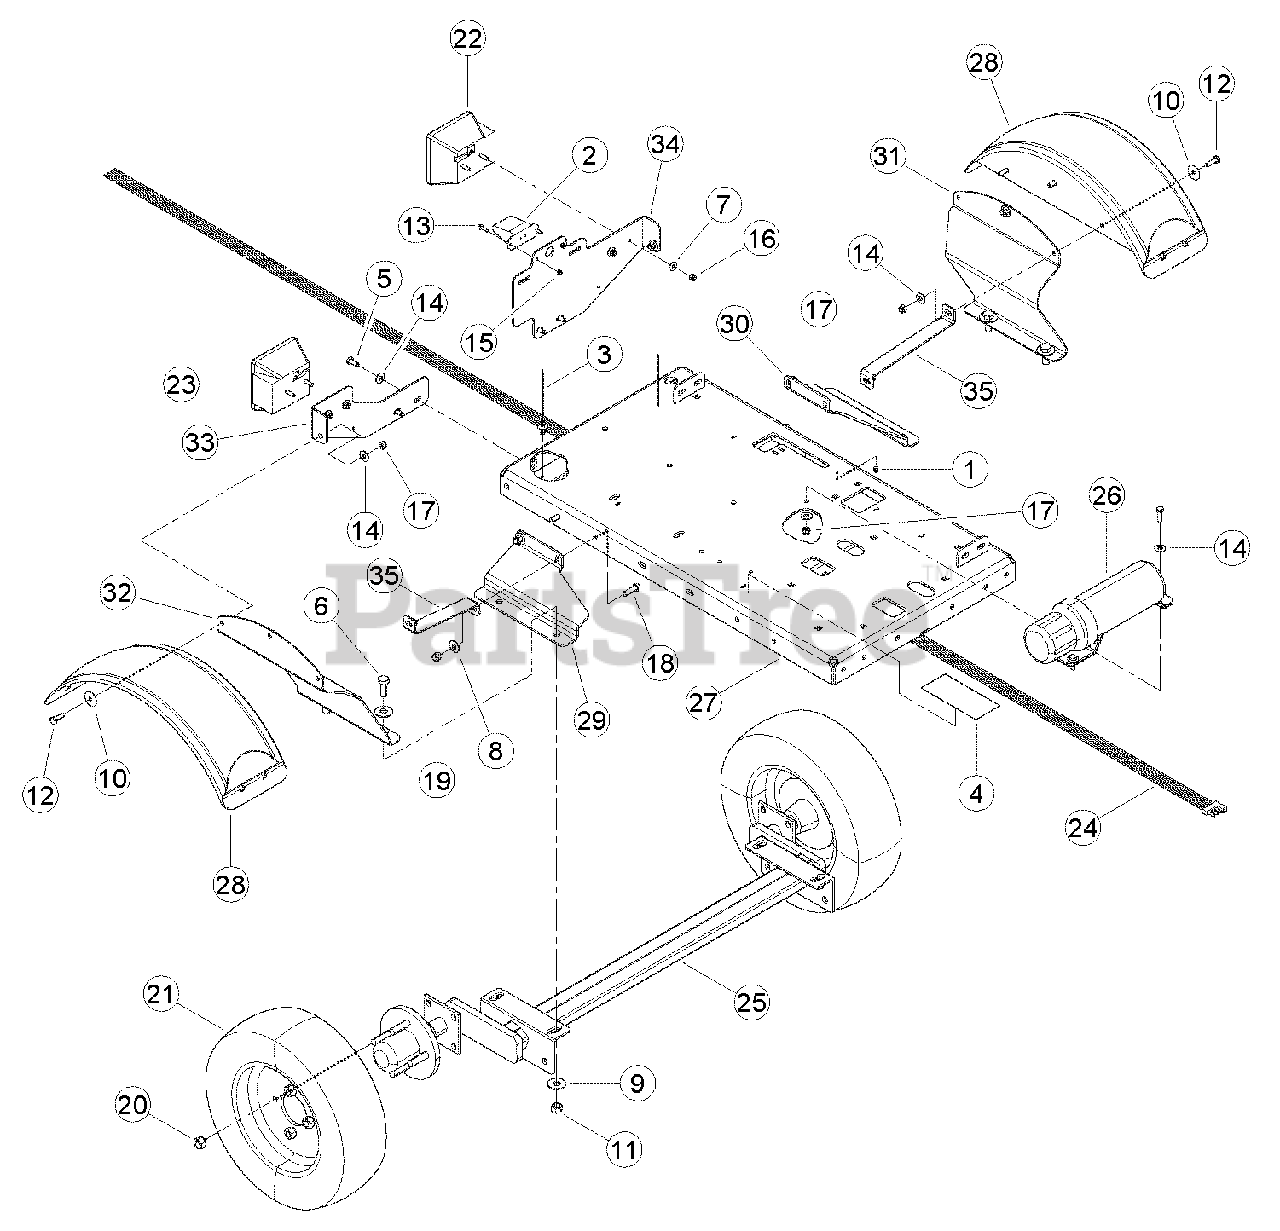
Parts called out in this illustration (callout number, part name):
1	FITTING, 1/4 SELF-TAP GREASE
2	LIGHT, LICENSE PLATE
3	TIE, DOME FIR TREE
4	DECAL, MUTILINGUAL MANUAL
5	BOLT, 5/16 X 3/4 HEX HD GR5 ZP
6	BOLT, 1/2 X 1-1/4 HEX HD GR5 NC ZP
7	WASHER, 1/4 FLAT ZP
8	WASHER, 3/8 FLAT ZP
9	WASHER, 1/2 FLAT ZP
10	WASHER, 5/16 FENDER ZP
11	NUT, 1/2 CENTERLOCK GRB ZP
12	BOLT, 5/16 X 1 HEX HD GR5 NC ZP
13	SCREW, #10 X 3/4 HEX TAP SC
14	WASHER, 5/16 FLAT ZP
15	NUT, 8-32 NYLOCK
16	NUT, 1/4 NE NYLOCK ZP
17	NUT, 5/16 NE NYLOCK ZP
18	BOLT, 3/8 X 1-1/4 HEX HD GR5 ZP
19	NUT, 3/8 NE NYLOCK ZP
20	NUT, 1/2-20 WHEEL
21	TIRE + WHEEL ASSEMBLY 4.80-8
22	LIGHT, LH TAIL
23	LIGHT, RH TAIL
24	HARNESS, TRAILER LIGHT
25	AXLE, 1000LB TORSION
26	CONTAINER, MANUAL
27	WELDMENT, CHIPPER TRAILER
28	FENDER, BLACK PLASTIC DRILLED
29	SUPPORT, AXLE FENDER RH (VIN 5VJAA0017AW002656 AND ABOVE)
29	SUPPORT, AXLE FENDER RH (VIN 5VJAA0017AW002655 AND BELOW)
30	SUPPORT, AXLE FENDER LH (VIN 5VJAA0017AW002656 AND ABOVE)
30	SUPPORT AXLE FENDER (VIN 5VJAA0017AW002655 AND BELOW)
31	SHEET, MOUNT FENDER LH (VIN 5VJAA0017AW002656 AND ABOVE)
31	SHEET, MOUNT FENDER LH (VIN 5VJAA0017AW002655 AND BELOW)
32	SHEET, MOUNT FENDER RH (VIN 5VJAA0017AW002656 AND ABOVE)
32	SHEET, MOUNT FENDER RH (VIN 5VJAA0017AW002655 AND BELOW)
33	BRACKET, LIGHT RH
34	BRACKET, LIGHT LH
35	BRACKET, FENDER SUPPORT (VIN 5VJAA0017AW002656 AND ABOVE)
35	BRACKET, FENDER (VIN 5VJAA0017AW002655 AND BELOW)
